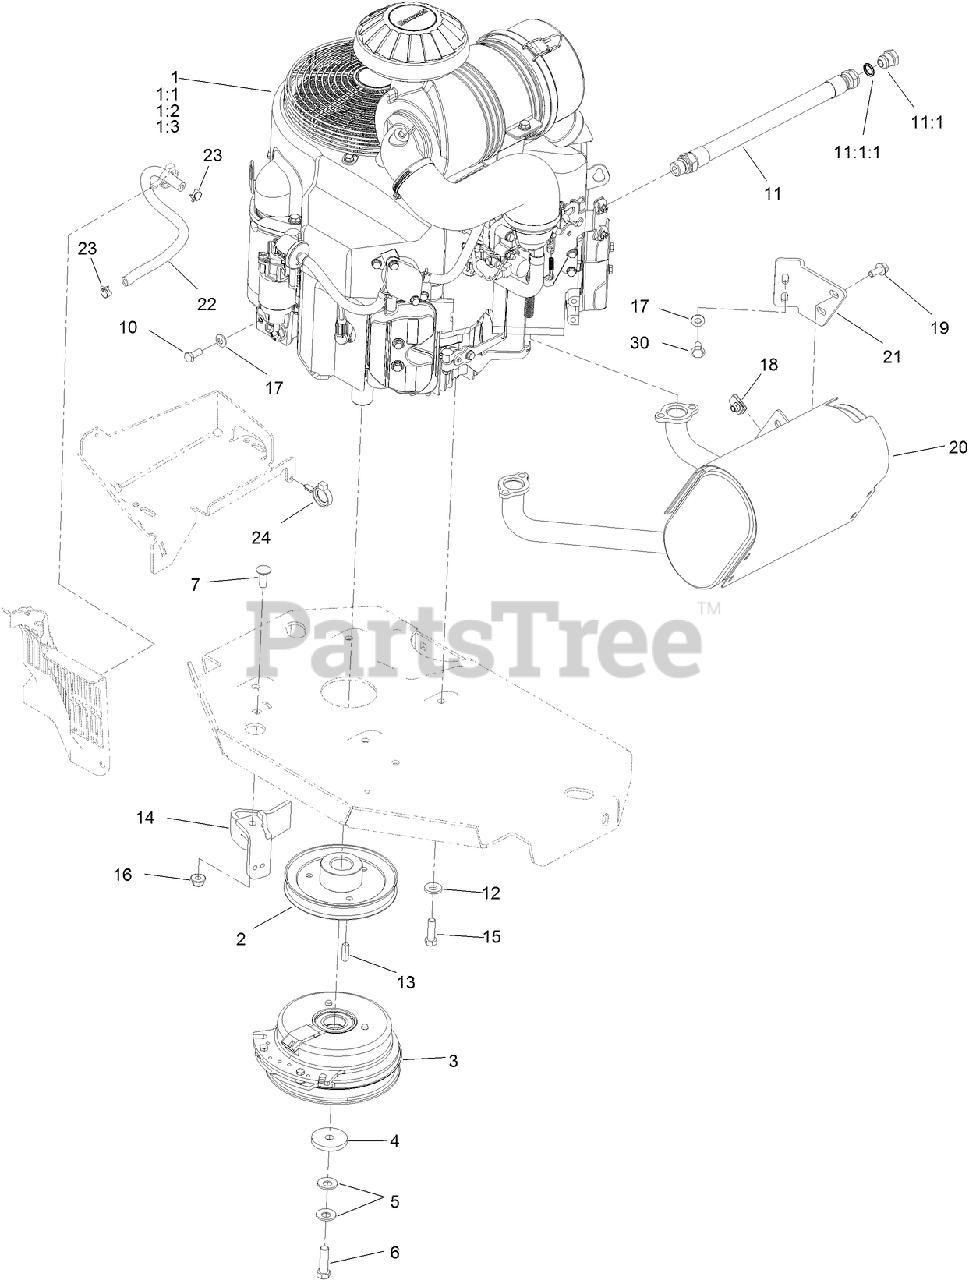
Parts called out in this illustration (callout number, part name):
1:1	KAWASAKI 49065-2078 ENGINE OIL FILTER
1:2	KAWASAKI 11013-7044 ENGINE AIR FILTER
1:3	KAWASAKI 11013-7045 SAFETY FILTER
2	SHEAVE
3	CLUTCH KIT
4	WASHER-CLUTCH
5	WASHER-SPRING
6	SCREW-HH, W/LOCTITE
7	SCREW-CARR
10	SCREW-HH
11	ENGINE OIL DRAIN HOSE ASM
11:1	PLUG-HH
11:1:1	O-RING
12	WASHER-BELLEVILLE
14	CLUTCH-ANCHOR
15	SCREW-HH
16	NUT-HF, NI
17	WASHER-SPRING
18	NUT-U
19	SCREW-HH
20	MUFFLER
21	BRACKET-MUFFLER
22	HOSE-FUEL
23	CLAMP-HOSE
24	CLAMP-HOSE
30	SCREW-HHF
